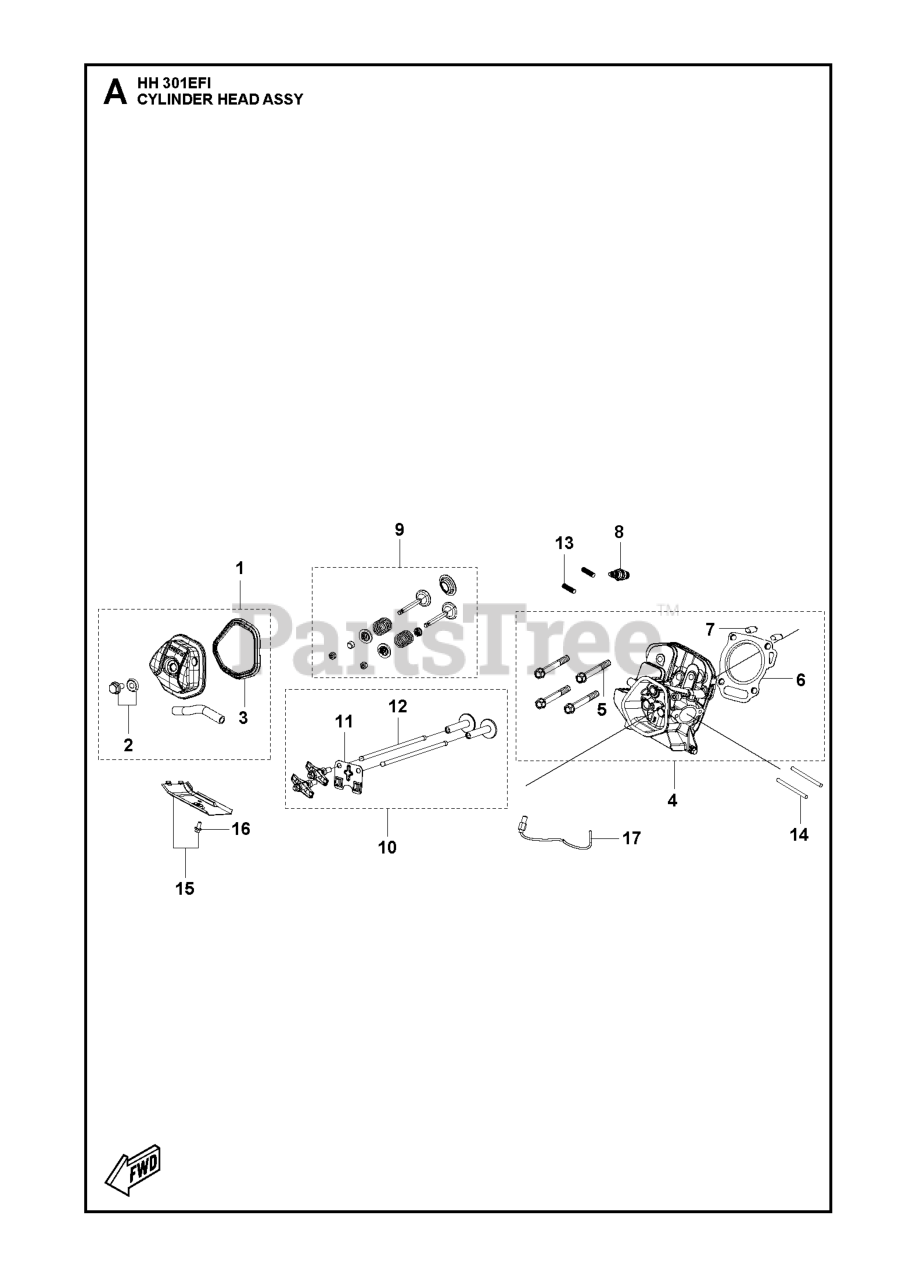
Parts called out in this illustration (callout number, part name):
1	CYLINDER COVER CYLINDER HEAD C
2	BOLT KIT
3	GASKET CYLINDER HEAD COVER GAS
4	CYLINDER HEAD KIT
6	GASKET CYLINDER HEAD GASKET
7	PIN LOCATION PIN
8	SPARK PLUG HQT-7 RESISTOR
10	VALVE KIT ROCKER ARM KIT
11	PLATE PUSH ROD GUIDE PLATE
12	PUSH ROD PUSH ROD SET
15	DEFLECTOR AIR DEFLECTOR KIT
16	BOLT
17	SENSOR TEMPERATURE SENSOR
